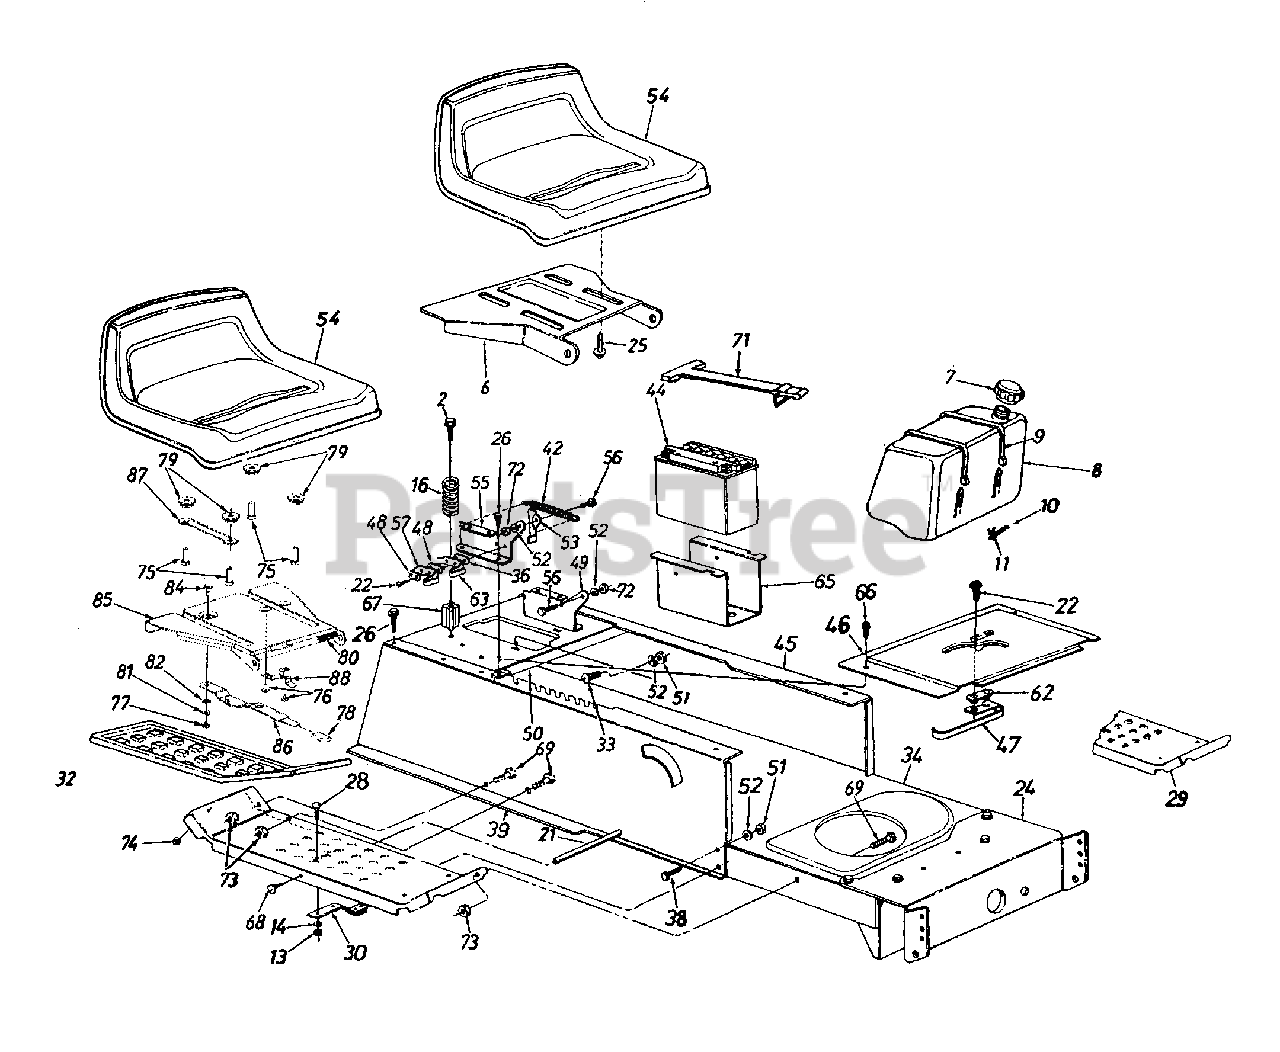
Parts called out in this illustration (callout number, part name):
2	Hex Tap Scr. 5/16-18 x 3.25"
7	Fuel Cap
8	Fuel Tank (1.75 Gal)
8	Fuel Tank (3 Gal.)
9	Tie Strap
10	Fuel Line
11	Hose Clamp
13	Hex Nut 1/4-20 Thd.
14	L-Wash. 1/4" I.D.
16	Compression Spring
21	Running Board Rod
22	Hex AB-Tap Scr. #8 x .50" Lg.
23	Speed Nut #10Z
25	Hex Tap Scr. 3/8-16 x .62" Lg.
26	Hex Wash. Hd. AB-Tap Scr.5/16 x .75"
28	Carriage Bolt 1/4-20 x .62"
32	Rubber Foot Pad-L.H."
32	Rubber Foot Pad-R.H.
32	Abrasive Foot Pad
36	Insulator Boss Plate
37	Fl-Wash. .344" I.D. x .625" O.D.
38	Hex Bolt 5/16-18 x .75" Lg.
44	12-V Battery
47	Reverse Safety Switch
48	Insulator Plate
49	Seat Pivot Brkt. Support-L.H.
52	L-Wash. 5/16" LID.
53	Seat Lift Brkt.
54	Seat 8-7/8" High
54	Seat 8-7/8" High (Yellow)
54	Seat 10-5/8" High
54	Seat 10-5/8" High (Yellow)
54	Seat 14-1/4" High
54	Seat 14-1/4" High (Yellow)
54	Seat 14-1/4" High w/ Drain holes
55	Seat Pivot Brkt. Support-R.H.
56	Shld. Bolt .437" Dia. x .268"
57	Spring Switch (Seat-Outer)
58	Hex TT Tap Scr. 5/16-18 x 7/8"
62	Insulatop Nut Plate
63	Safety Switch (Seat-Inner)
65	Battery Tray
66	Truss Mach. B-Tap Scr.#10 x .5" Lg.
67	Spring Spacer
68	Truss Mach. Scr. 5/16-18 x .75"
69	Hex Bolt 5/16-18 x .75" Lg.
70	Snap Bushing
71	Battery Retainer Strap
72	Hex Nut 5/16-18 Thd.
73	Hex Sems Nut 5/16-18 Thd.
74	Hex Sems Nut 1/4-20 Thd.
75	Shoulder Screw 3/8-16 x .5
76	Hex Wash. Hd. B-Tap Scr.
77	Hex Flanged L-Nut 1/4-20 Thd.
78	Seat Adjustable Grip
79	Spacer
80	Compression Spring 1.5" Lg.
81	Spring Wash. .265" I.D.
82	Fl-Wash. .344" I.D. x .62" O.D.
84	Shld. Bolt .34" x 1/4 -20 Thd.
87	Seat Selector
88	Seat Stop
89	Stop Rod
90	Hex Nut 3/8-16
91	Lock Washer
